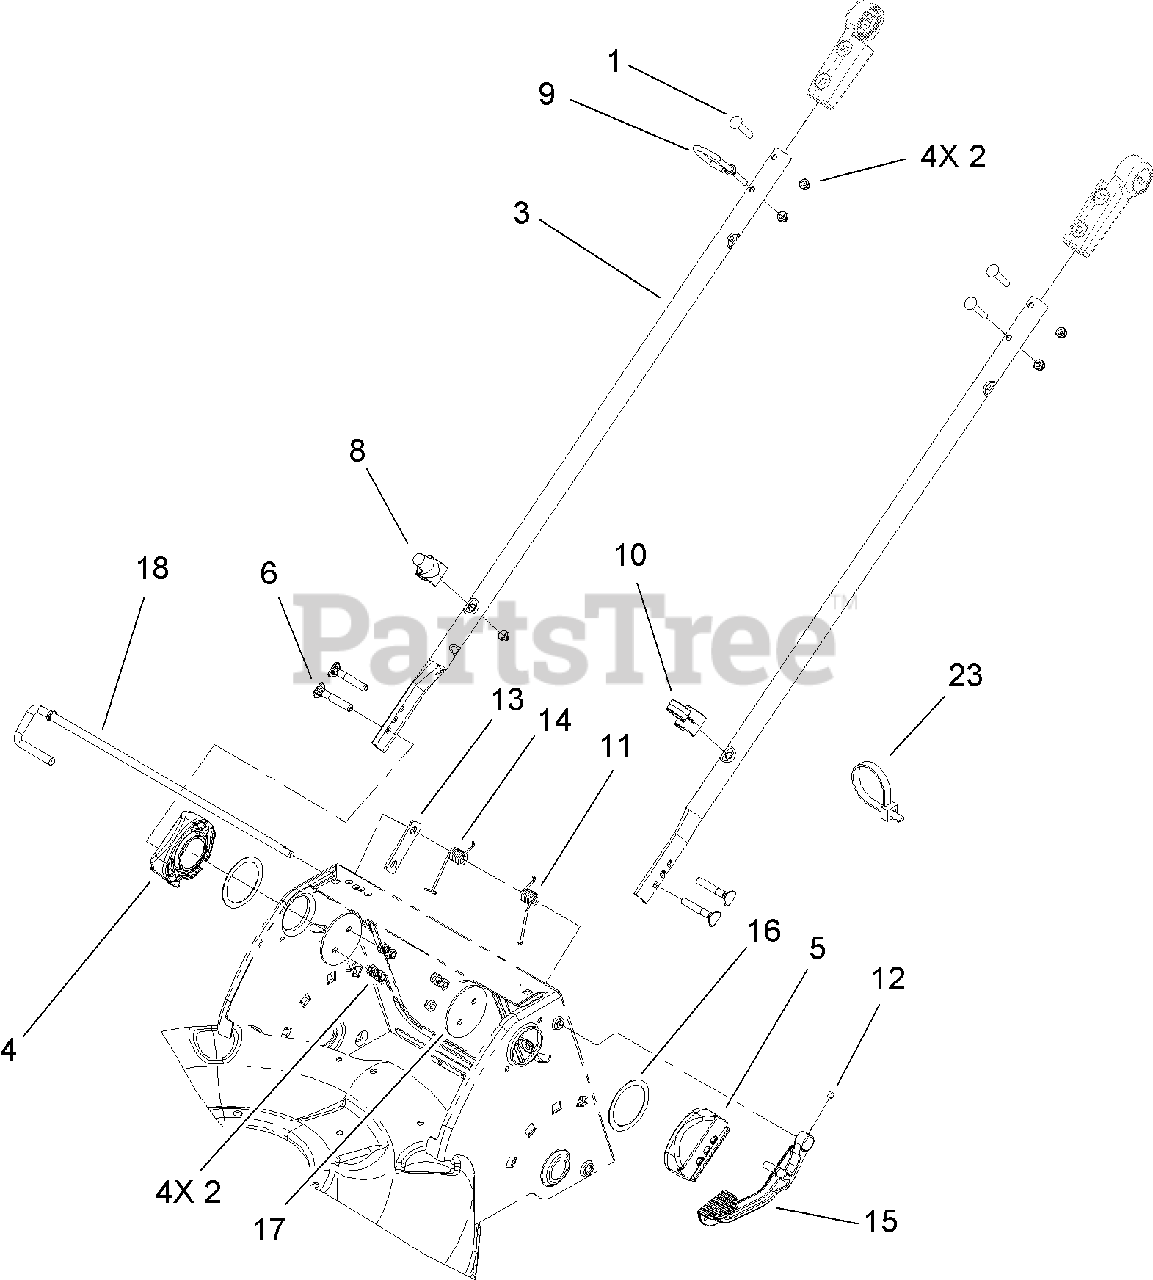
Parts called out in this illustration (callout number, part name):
1	SCREW-CARR
2	NUT-LOCK, NI
4	MOUNT-HANDLE, RH
5	MOUNT-HANDLE, LH
8	GUIDE-ROPE, LOWER
9	GUIDE-ROPE, UPPER
10	Guide-Cable
11	SPRING-TORSION, LH
12	SCREW-SET
13	SPRING-TORSION, RH
14	PLATE-LOCK, HANDLE
15	LEVER-RELEASE
16	WASHER-NYLON
18	ROD-RELEASE
23	STRAP-TIE
